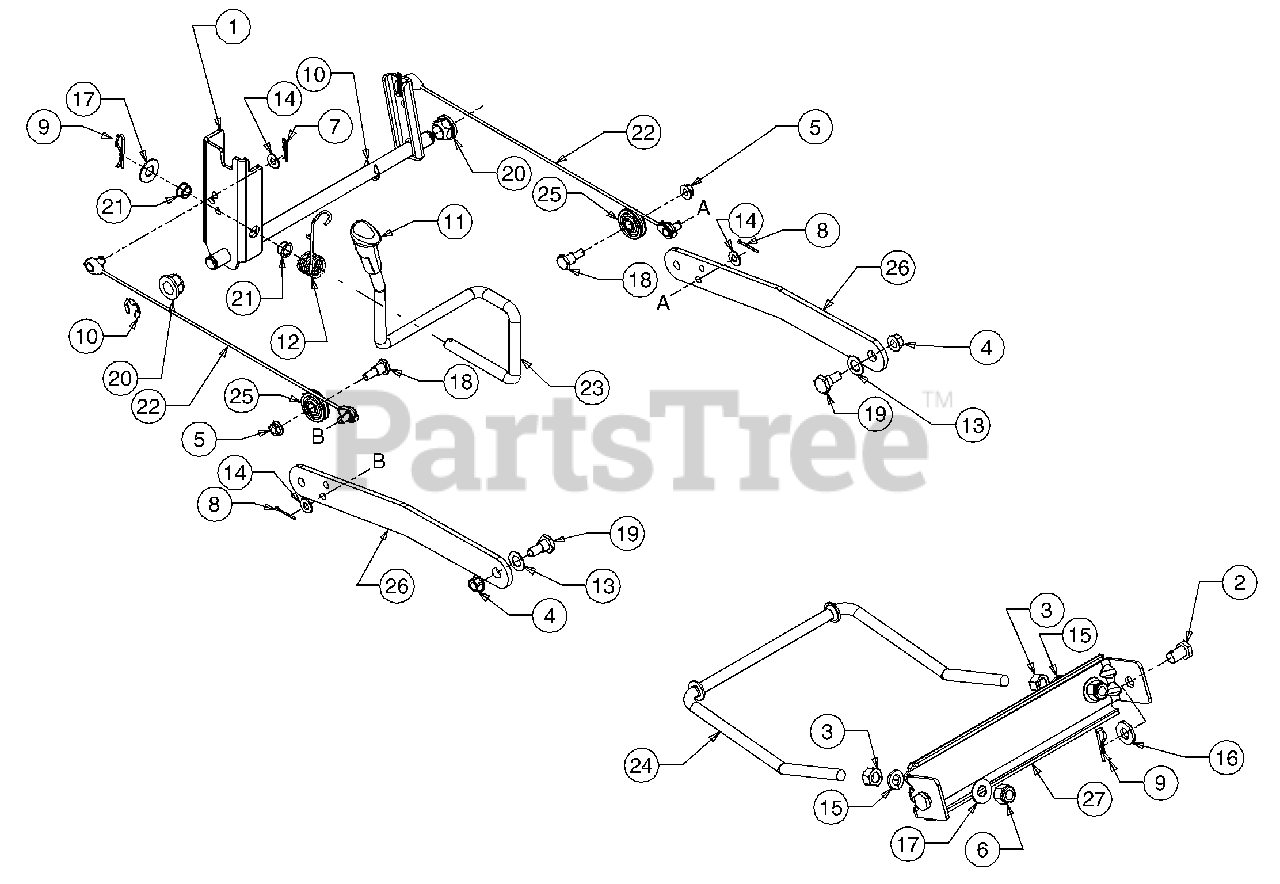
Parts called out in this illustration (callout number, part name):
2	Pin, Clevis, .50 Dia x .78 Lg
3	Nut, Hex, 1/2-13, Gr5
4	Nut, Flange Lock, 3/8-16
5	Nut, Flange Lock, 5/16-18, Gr5
6	Nut, Hex Lock, 1/2-13, Gr8, Nylon
7	Pin, Cotter, .072 Dia. x 1.13 Lg
8	Pin, Cotter, 3/32, 1.0
9	Pin, Click, .092 x 1.64 Lg
10	E-ring, .625 Dia. Shaft
11	Knob
12	Spring, Torsion
13	Washer, Flat, .53 x .93 x .050
14	Washer, Flat, .344 x .688 x .065
15	Washer, Lock, 1/2, Regular Duty
16	Washer, Flat, .531 x 1.062 x .134
17	Washer, Flat, .510 x 1.120 x .060
18	Screw, Hex Cap, 5/16-18x.620 Gr2
19	Shoulder Screw, 3/8-16
20	Bearing, Hex Flange
21	Bearing,Flange, Snap .500 ID
22	Cable, Lift, 16.16 Lg
23	Handle, Lift
24	Rod, Deck, Front Adjustment .5" Dia
25	Pulley, Roller
